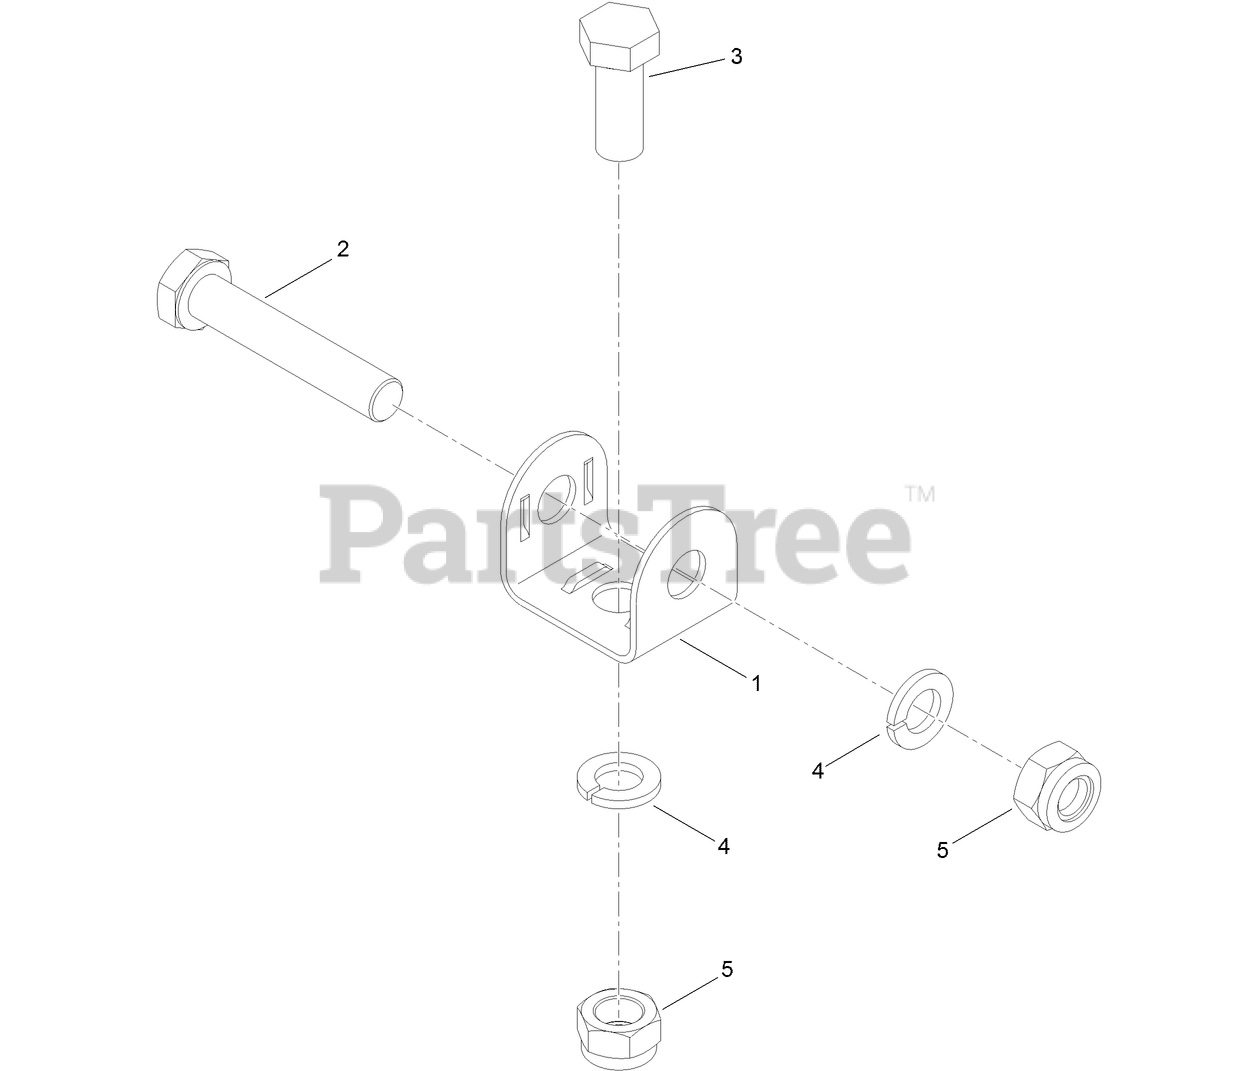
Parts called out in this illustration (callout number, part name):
1	MOUNT-LIGHT
2	SCREW-HH
3	SCREW-HH
4	WASHER-LOCK
5	NUT-HEX
